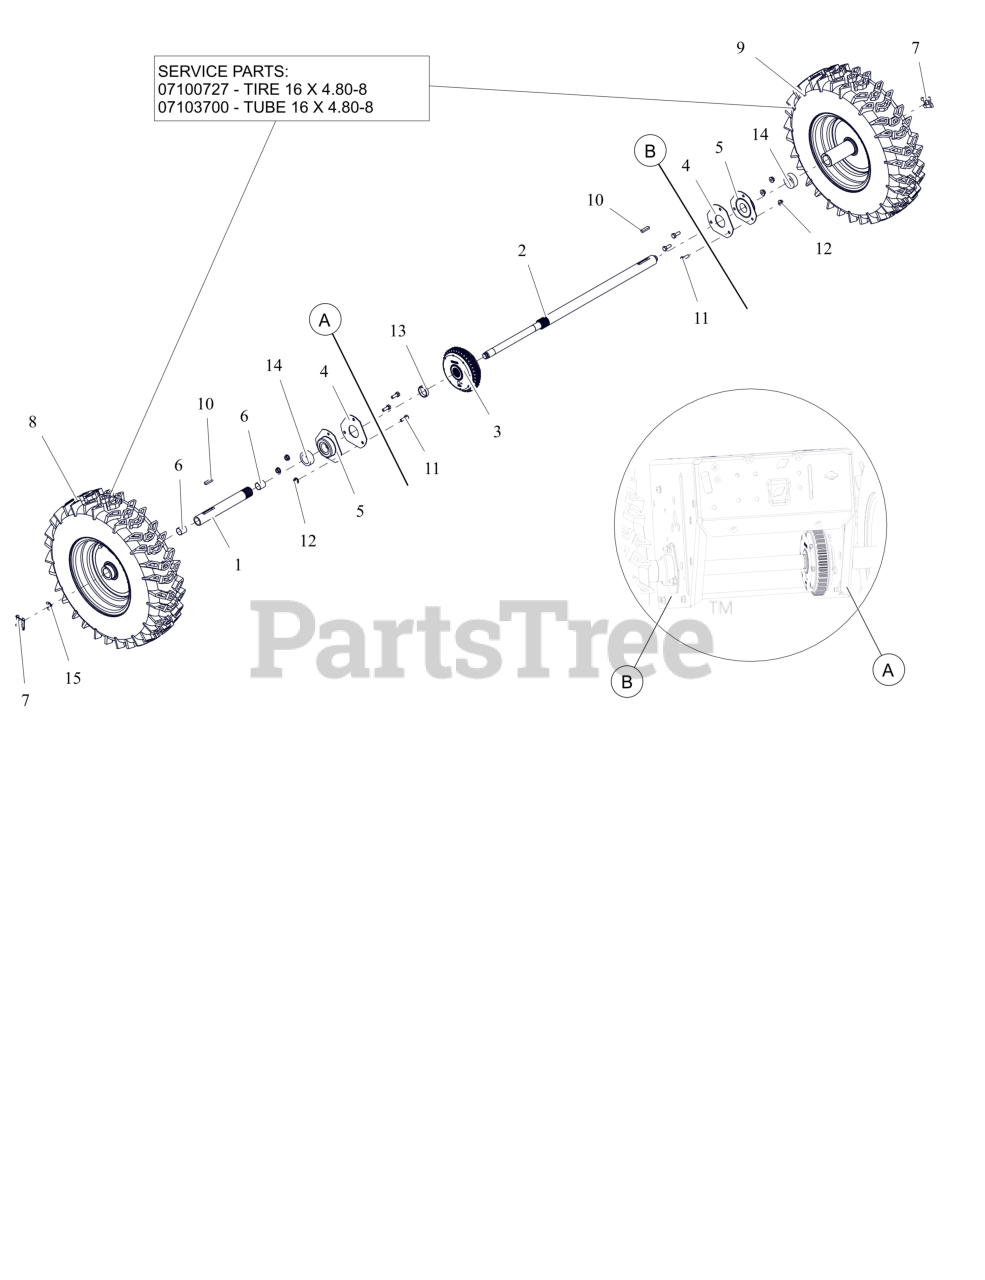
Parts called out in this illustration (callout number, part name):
1	AXLE, SHORT-AUTO W/BUSHINGS
2	AXLE, LONG-PRO AUTO DIFF
3	DIFFERENTIAL, AUTOMATIC
4	PLATE, BEARING SPACER
5	BRG-FLG 1.003/1.000 3 BOLT
6	BSHG-SLV .706X.764X.75 BRZ
7	CLIP, SNAP .625 DIA
8	TIRE/WHEEL RH 16X4.8-8 DIFF T2
8	SNOW TIRE, 16/4.80-8 K478 DIRECTIONAL
8	TIRE TUBE, 16X4.80/4.00-8 4 PLY TR13 STRAIGHT VALVE
9	TIRE/WHEEL LH 16X4.8-8 DIFF T2
9	SNOW TIRE, 16/4.80-8 K478 DIRECTIONAL
9	TIRE TUBE, 16X4.80/4.00-8 4 PLY TR13 STRAIGHT VALVE
10	KEY-RECT .25X.188X1.00
11	BLT, HEX .25-20X.75 G5 ZCC
12	NUT-LK-CTR-FLG .25-20 ZC120
13	BSHG, SLV 1.062X1.228X.268
14	SPACER, PRO AXLE BEARING
15	RG-RTNG-EXT .625X.042
